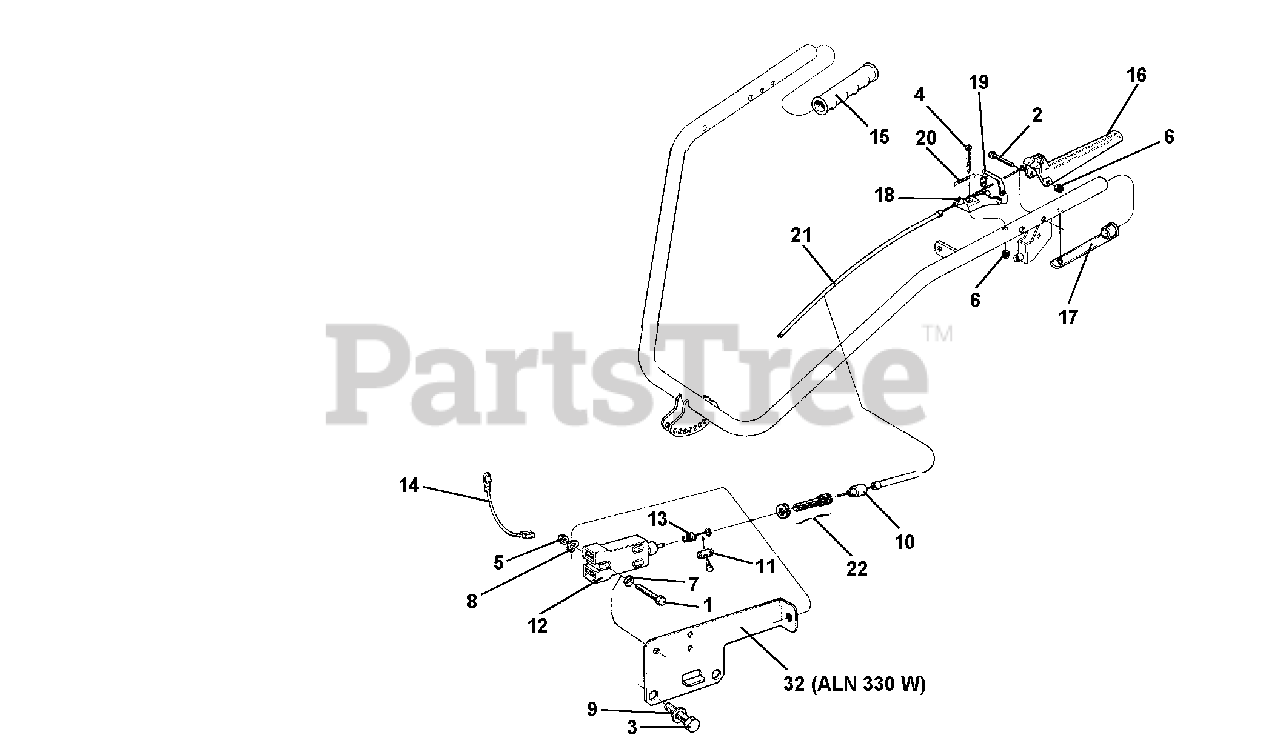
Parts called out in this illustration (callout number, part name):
1	SCREW TE M4 X 25
2	SCREW TE M6 X 45
3	SCREW TE M8 X 12
4	SCREW TSV M6 X 40
6	NUT, SELF LOCKING M6
7	FLAT WASHER 4.3
8	LOCK WASHER B 4.3
9	WASHER, LOCK 8.4
10	END, SHEATH
11	CABLE CLAMP
12	STOP SWITCH
13	SWITCH SPRING
14	SWITCH CABLES
16	MOVABLE MOTOR STOP BODY
18	SHEATH LOCK
19	MOVABLE BODY LOCK
21	SHEATH CABLE
22	ADJUSTING SCREW
23	SUPPORT FOR ACME STOP SWITCH
